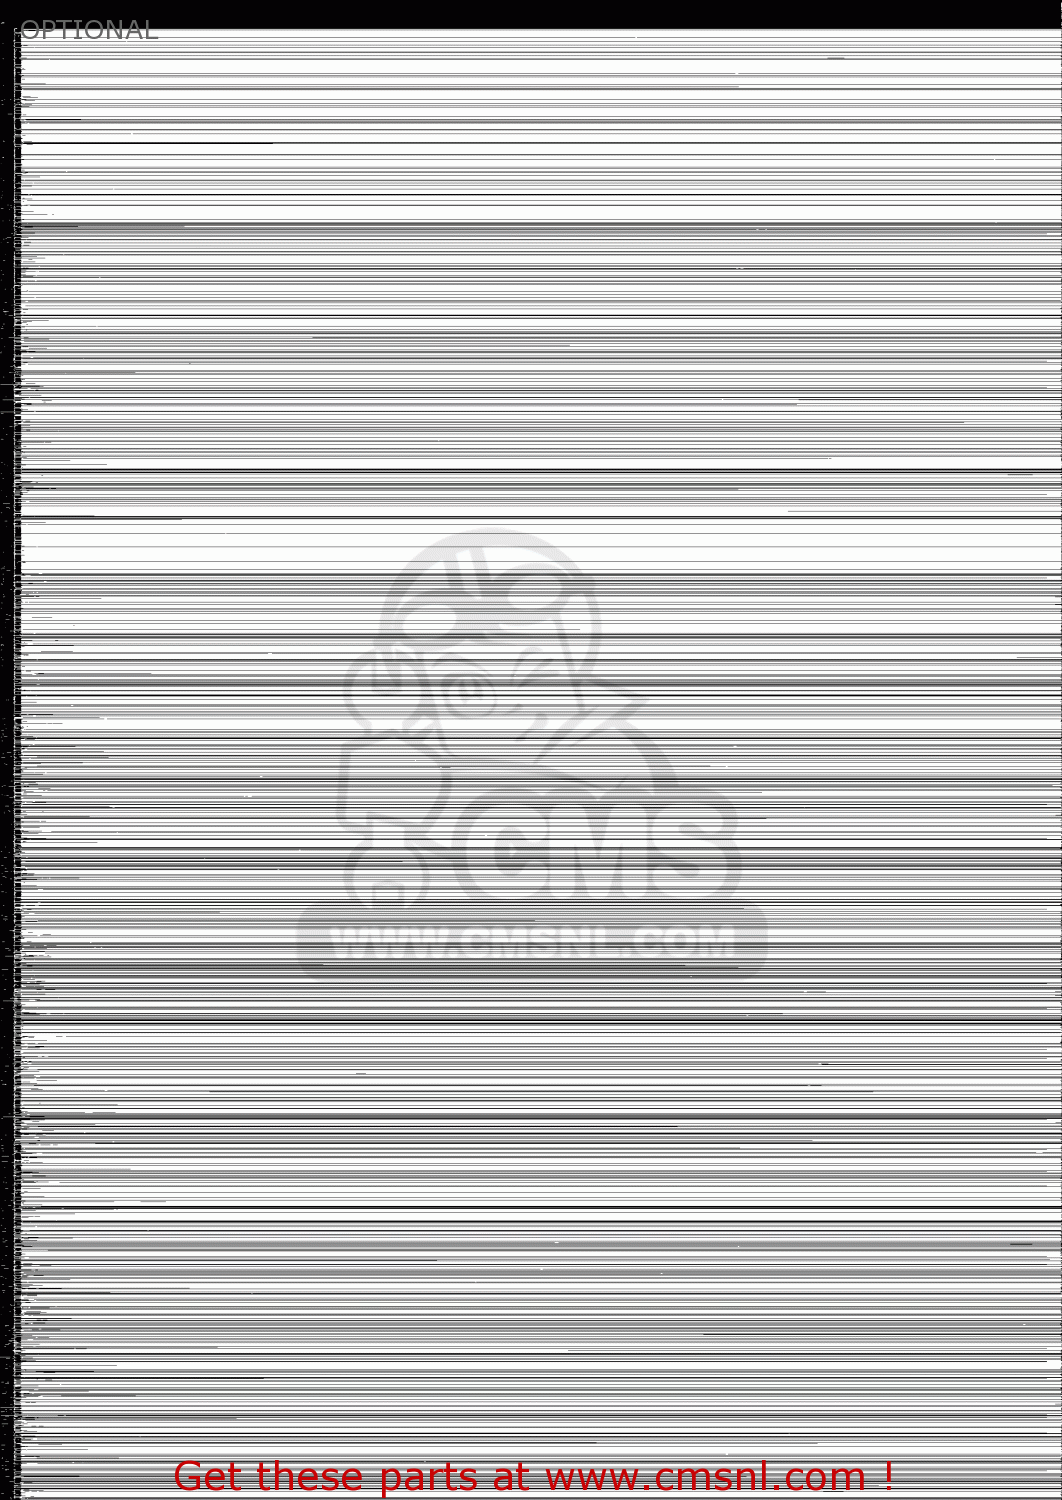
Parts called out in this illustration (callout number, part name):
1	GREASE,PBC FOR BRK PAD 20G
2	THREAD LOCK NO.1342
3	THREAD LOCK NO.1401 CLEAR 200G
4	LIQUID GSKT NO.1207B 100G BLK
5	GREASE(C)EP2 LITHIUM 150G
6	TUBE REPARING TOOL
7	SUZUKI MOLY PASTE
8	PAINT (BLACK)
9	PAINT,BLACK
10	GASKET SET
